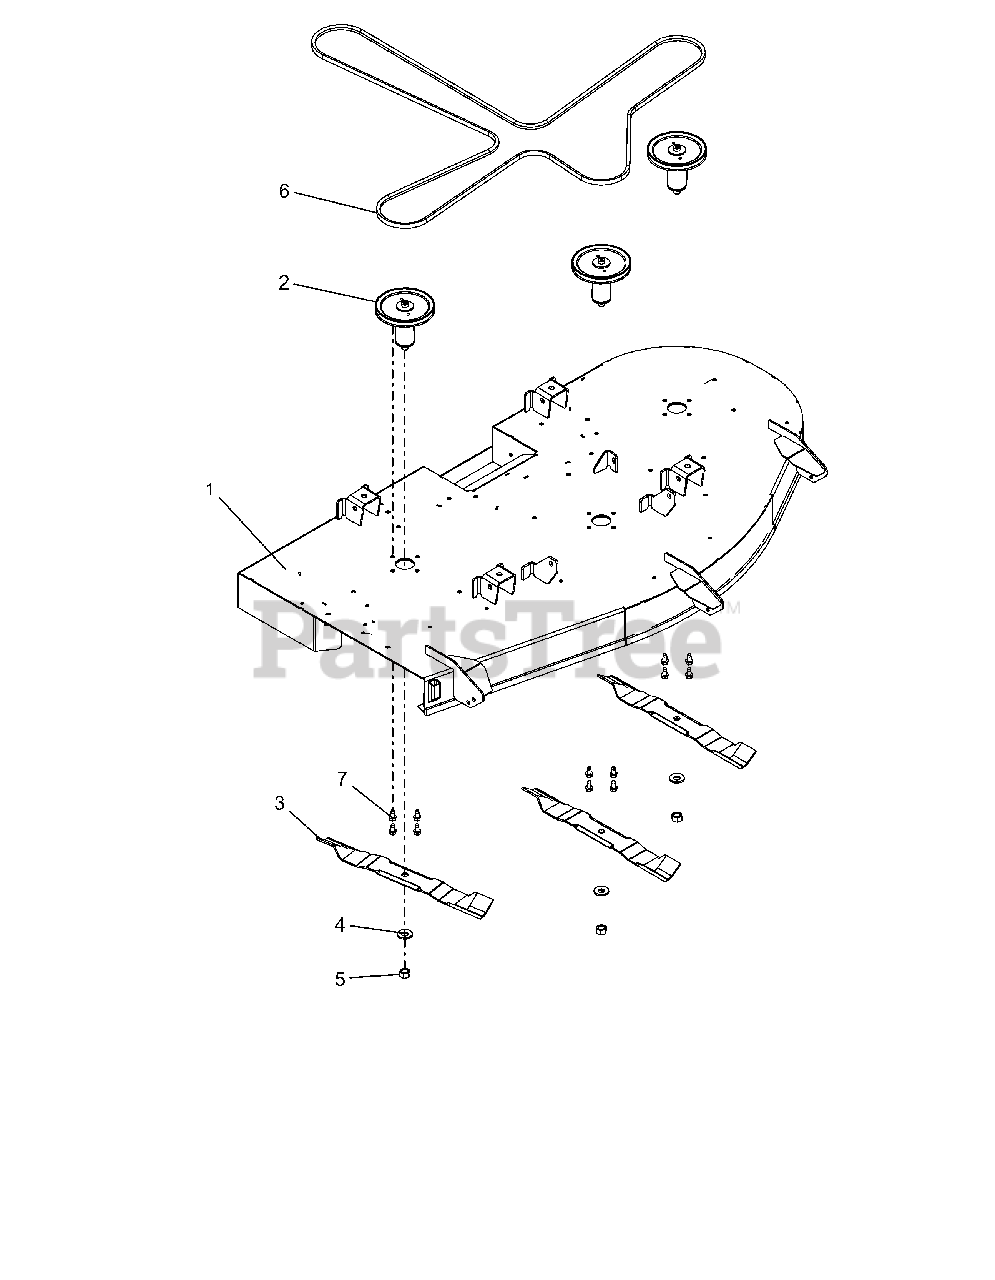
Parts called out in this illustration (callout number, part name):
1	KIT, 60" GRAVELY DECK W/DECALS
2	KIT, DECK SPINDLE ASM-60
3	BLADE, 21" 35 DEG
4	WSHR-BLVL .669X1.535X.138
5	NUT-HEX .62-18 YWZC
6	BELT, HA
7	@SCR-TAP .38-16X.75 HWH TR YWZ
